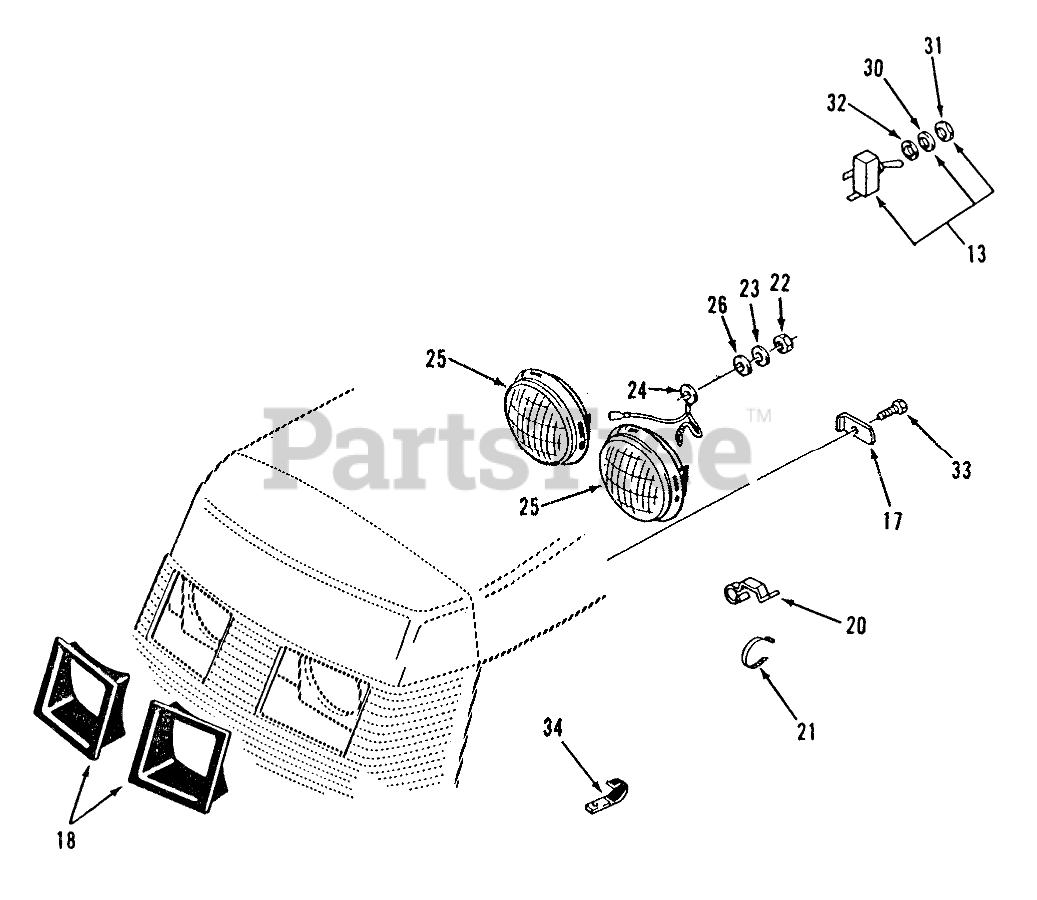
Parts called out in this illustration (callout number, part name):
13	SWITCH-LIGHTS
17	LOCK-HEADLIGHT
18	BEZEL-HEADLIGHT, RH
18	BEZEL-HEADLIGHT, LH
20	CLIP-WIRE
21	PLASTIC TIE
22	Nut
23	Washer-Lock
24	ASSY GROUND WIRE
25	HEADLAMP
26	WASHER 5/16 SAE
30	TAB-WASHER
31	NUT-HEX
32	Washer
33	Bolt
34	CLIP
36	TERMINAL 10
37	Terminal
